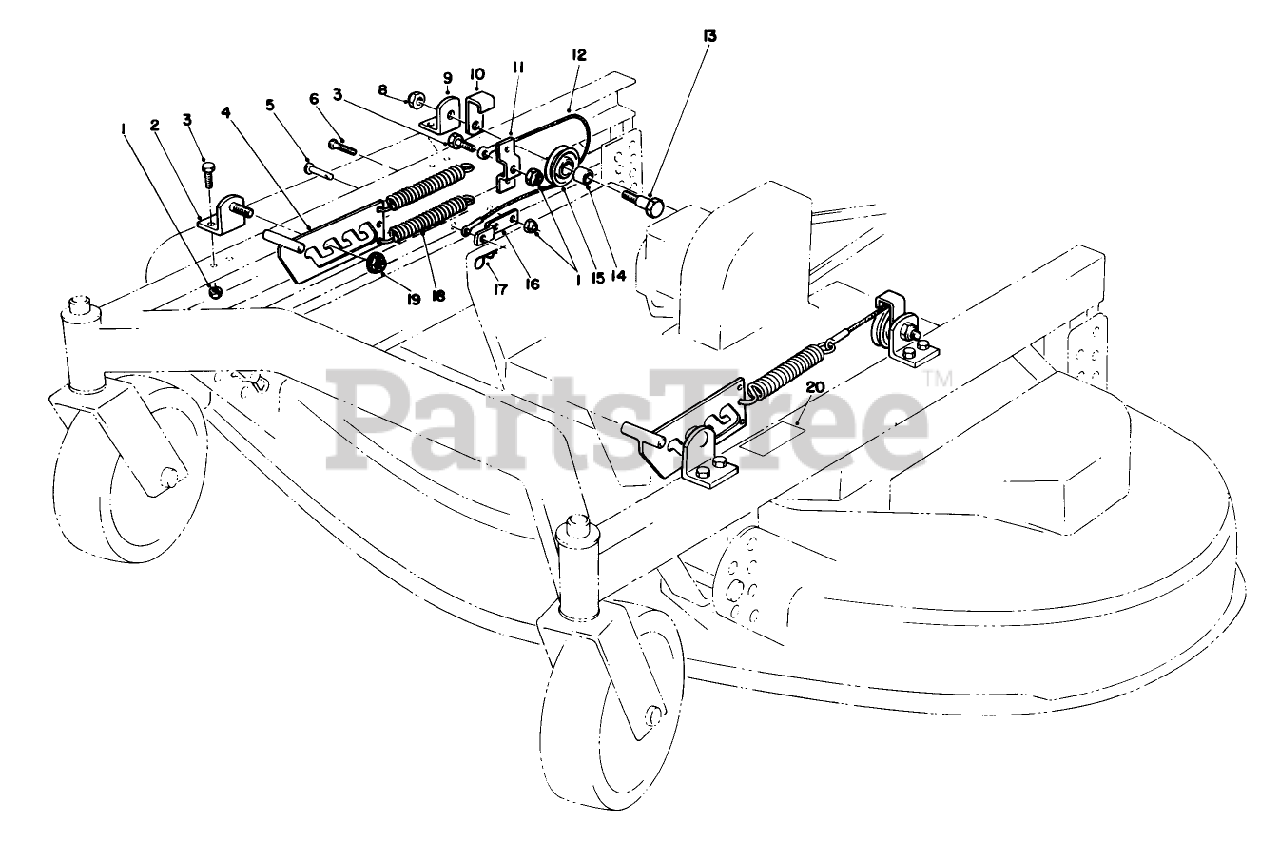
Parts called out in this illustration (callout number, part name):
1	NUT-LOCK, NI
2	Bracket-Control
3	SCREW-HH
4	Control-Tension
6	1/4-20 X 5/8 RD HD SC
8	NUT-LOCK, NI
9	Bracket-Pulley
10	CABLE RETAINER
11	SPRING BRACKET
12	CABLE
13	BOLT-SHOULDER
14	BUSHING
15	Pulley Assembly (Incl. Ref. # 14)
16	Bracket-Anchor
17	PIN-COTTER
18	EXTENSION SPRING
19	NUT-HF
20	DECAL-WARNING
